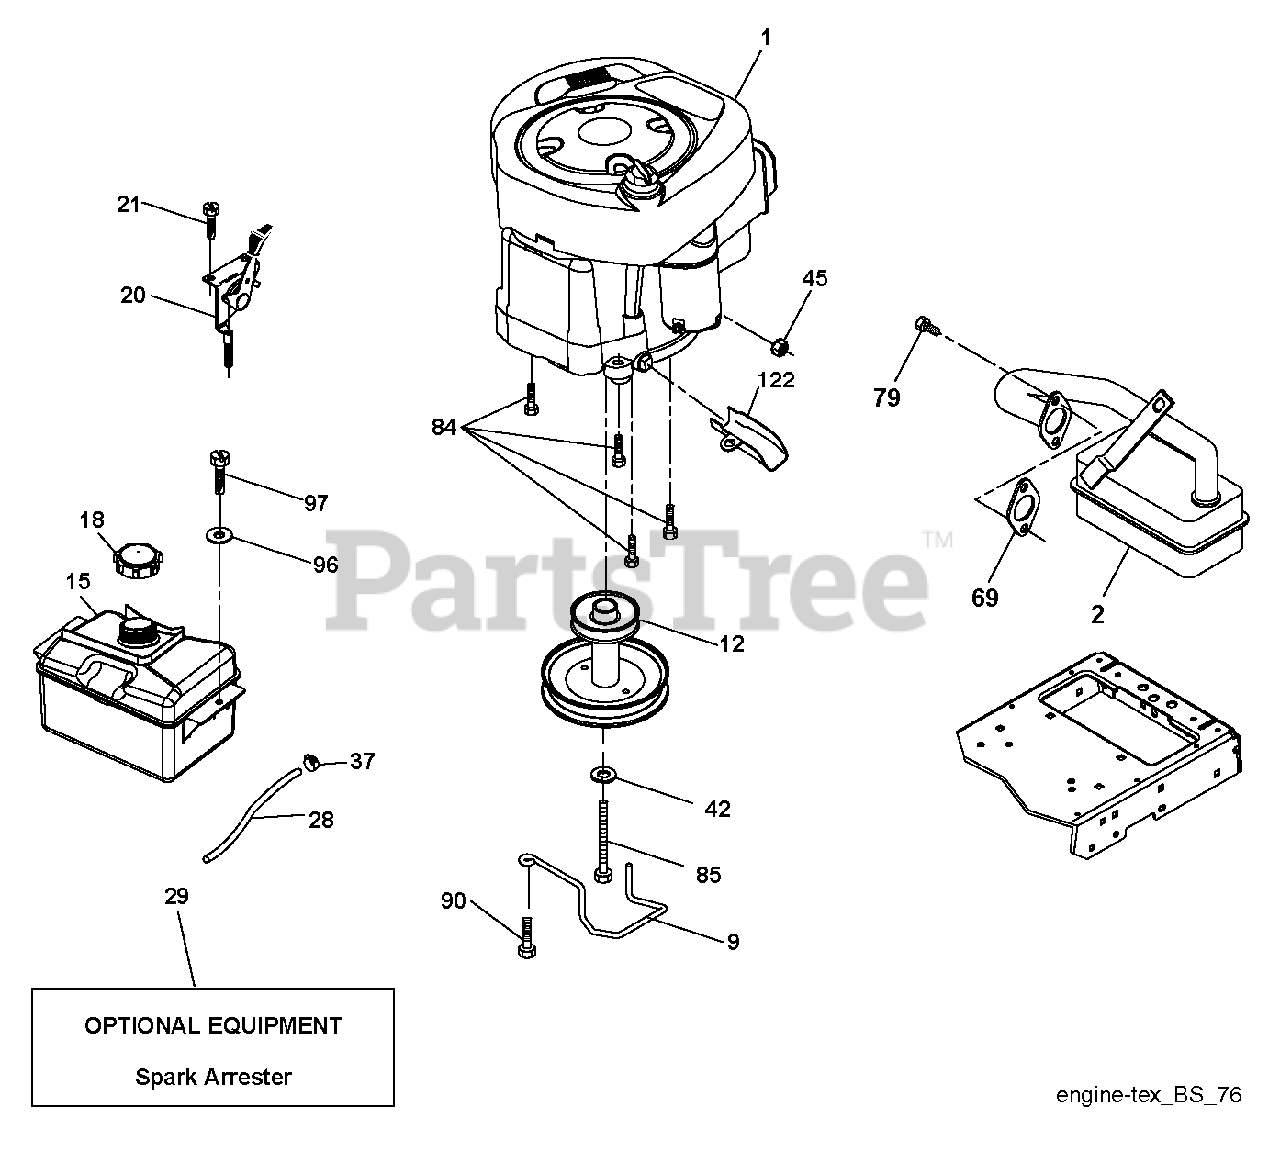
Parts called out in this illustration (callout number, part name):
2	MUFFLER.LT.BRIGGS.14HP.IC/OHV
9	KEEPER.BELT.ENGINE.3.25 (3 2)
12	PULLEY.ENG.CL.MECH.SLVR.LT/YT
15	FUEL.TANK.ASM.NON-EPA
18	CAP ASM.FUEL.2.25"FR.
20	CONTROL.TH/CK.COBRA.KO
21	SCREW.#10 X 0.750.BOS
28	LINE.FUEL.20
29	KIT.SPARK ARRESTOR 794945 B&S
37	HOSE CLAMP
42	LOCKWASHER
45	NUT
69	REPL BY 532 27 22-93
79	SCREW.SOCKET HD.5/16-1
84	SCREW.3/8-16
85	BOLT HEX 7/16-20X4-1/4"
90	SCREW 3/8-16X1
97	SCREW HEXWSHR 1/4-20X3/4
122	EXTENSION DRAIN OIL
